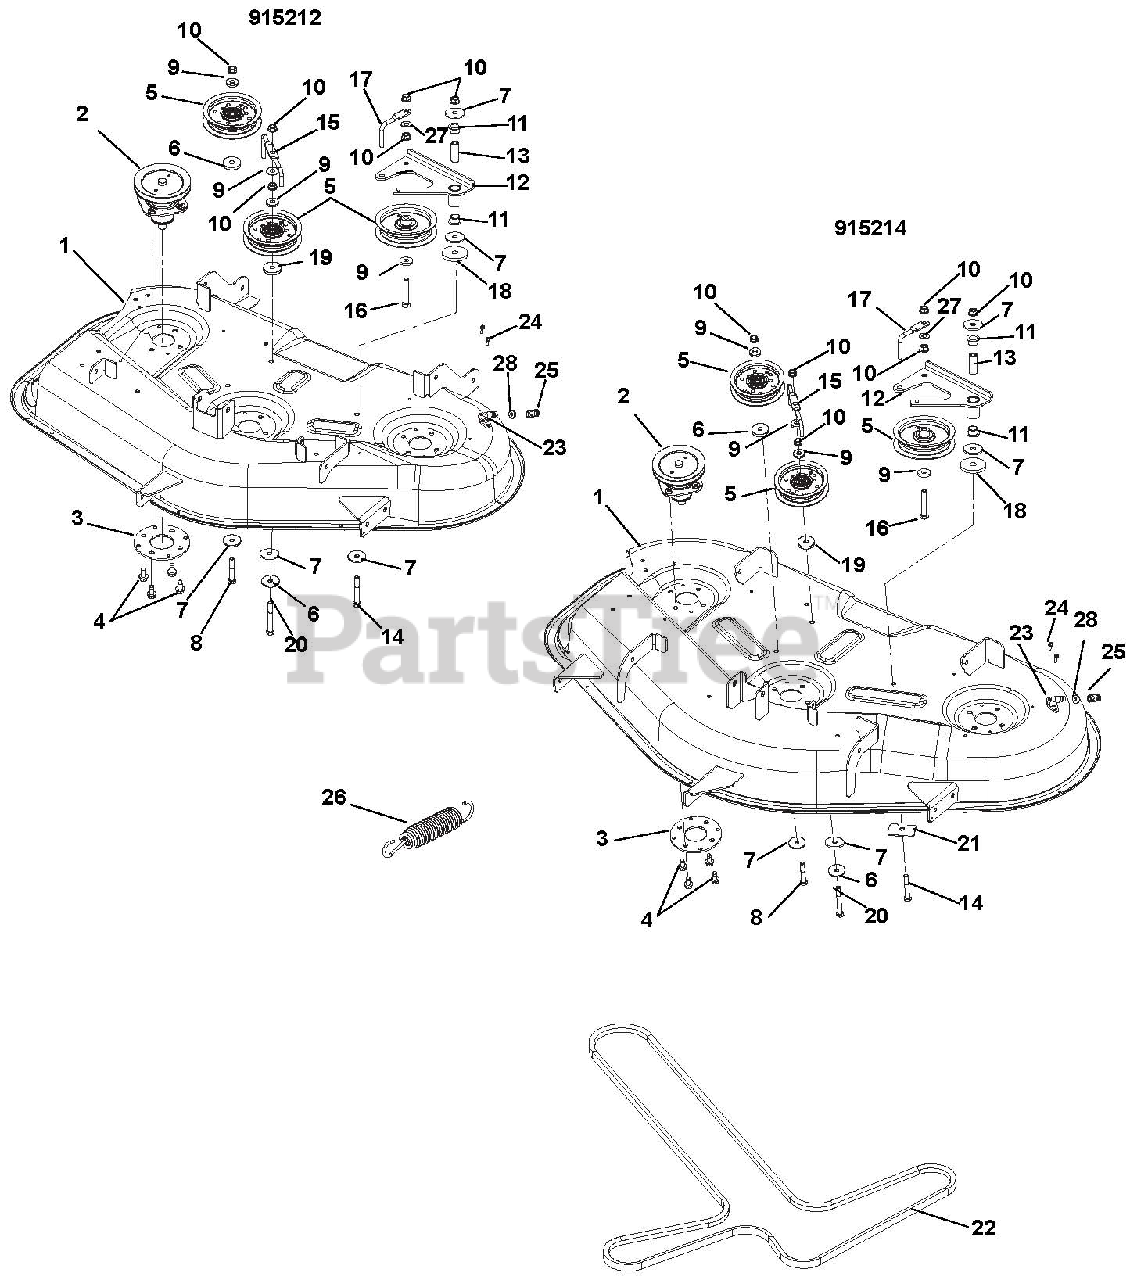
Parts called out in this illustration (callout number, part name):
1	Kit, Gravely 42" Deck with Decals
1	Kit, Gravely 50" Deck with Decals
2	Assembly, Spindle
3	Plate, Spindle
4	Screw, Tapping .38-16 x .75 Hex Washer Head
5	Assembly, Idler 4"
6	Washer, Flat Steel .406 x 1.50 x .245
7	Washer, Flat Steel .380 x 1.50 x .125
8	Bolt, Hex .38-16 x 2.25
9	Washer, Flat Steel .406 x 1.00 x .188
10	Nut, Locking Top Flange .38-16
11	Bushing, Flange, .625 x .750 x .500 x 1.00
12	Idler Arm
13	Spacer, .375ID x .625 OD x 1.66
14	Bolt, Hex .38-16 x 3.00
15	Belt Finger
16	Bolt, Hex .38-16 x 2.25
17	Wireform Belt Finger
18	Washer, Flat Steel .469 x 2.00 x .25
19	Washer, Flat Steel .438 x 1.00 x .083
20	Bolt, Hex .38-16 x 2.75
21	Plate, Deck
22	V-Belt, 4L Wrapped
23	Assy, Washout Port W/O Ring
24	Screw, Tapping .25-20 x .62 Hex Washer Head Thread Rolling
25	Coupling, Quick Disconnect
26	Extension Spring .135 x .98 x 6.0
27	Washer, Flat Steel .406 x .812 x .065
28	O-Ring .362 X .103 X .568
